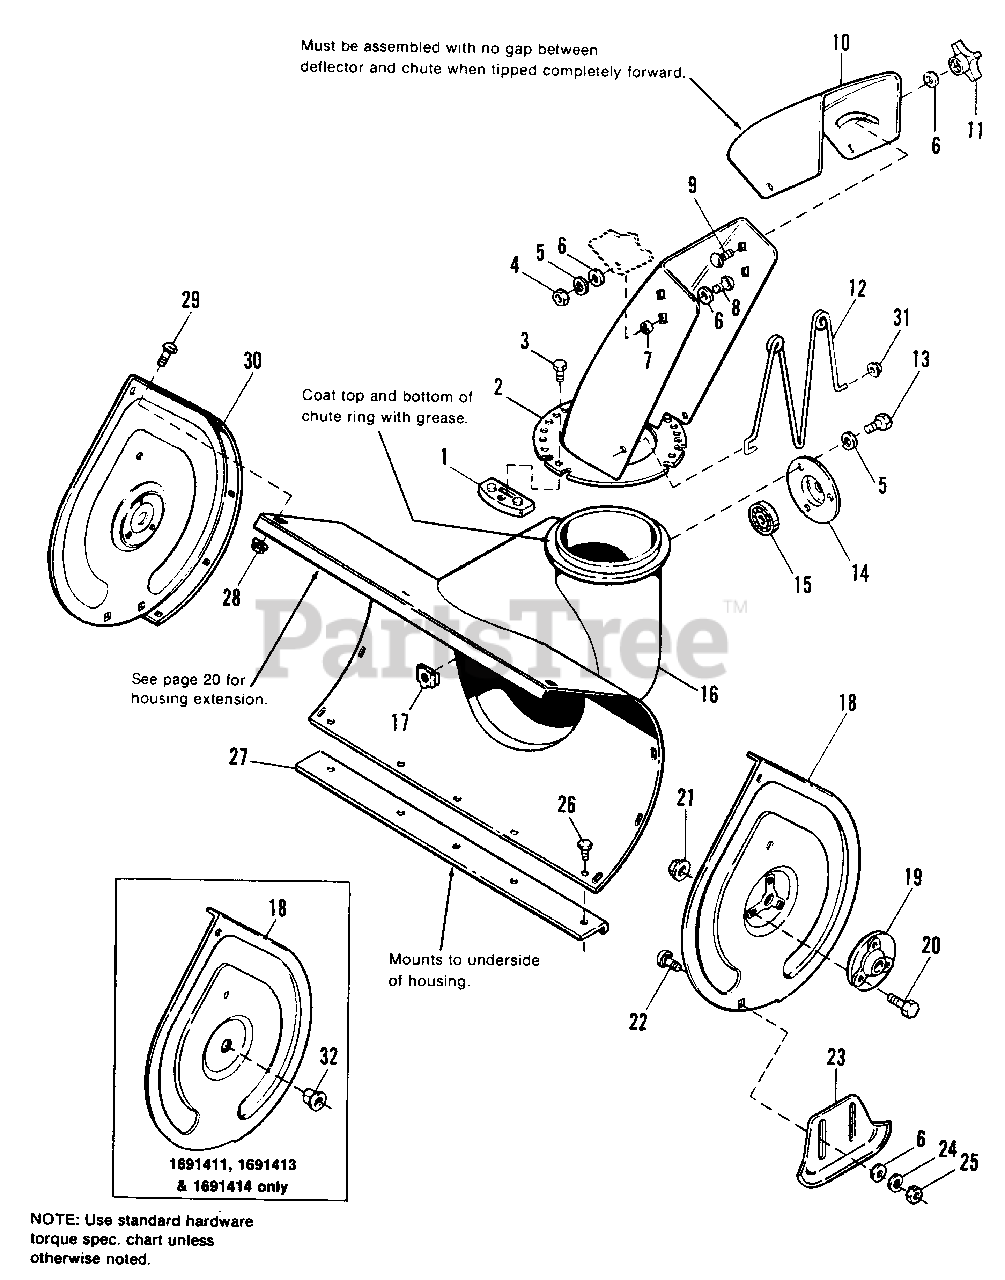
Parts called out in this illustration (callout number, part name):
1	HOLD DOWN, Chute
2	CHUTE ASSY.
3	SCREW, Plastite, #10
4	NUT, Hex, 5/16-18
5	LOCKWASHER
6	WASHER, 5/16
8	SCREW, Phil. Hd., 5/16-18 x 3/4
9	BOLT, Carriage, 5/16-18 x 7/8, Gr. 5
12	GUARD, Chute
13	SCREW, Hex, 5/16-18 x 5/8
14	RETAINER, Bearing
15	BEARING, Ball
16	AUGER HSG. ASSY.
17	NUT, Retainer, 5/16-18
18	AUGER HSG. END, L.H. (1691011, 1691181 only)
18	AUGER HSG. ENG, L.H. (1691411, 1691413, 1691414 only)
19	BEARING, Auger (1691011, 1691181 only)
20	SCREW, Hex, Whizlock, 5/16-18 x 3/4 (1691011, 1691181 only)
21	NUT, Hex., Fl. Hd. Lock, 5/16-18 (1691011, 1691181 only)
22	BOLT, Carriage, 3/8-16 x 3/4
24	LOCKWASHER, 3/8
25	NUT Hex, 3/8-16
26	SCREW, Taptite, 1/4-20 x 3/8
27	SCRAPER BLADE
28	NUT, Hex, 1/4-20 Wd. Fl. Lock
29	BOLT, Carriage, 1/4-20 x 1/2
30	AUGER HSG. END, R.H. (1691011, 1691181 only)
32	BUSHING (1691411, 1691413, 1691414 only)
